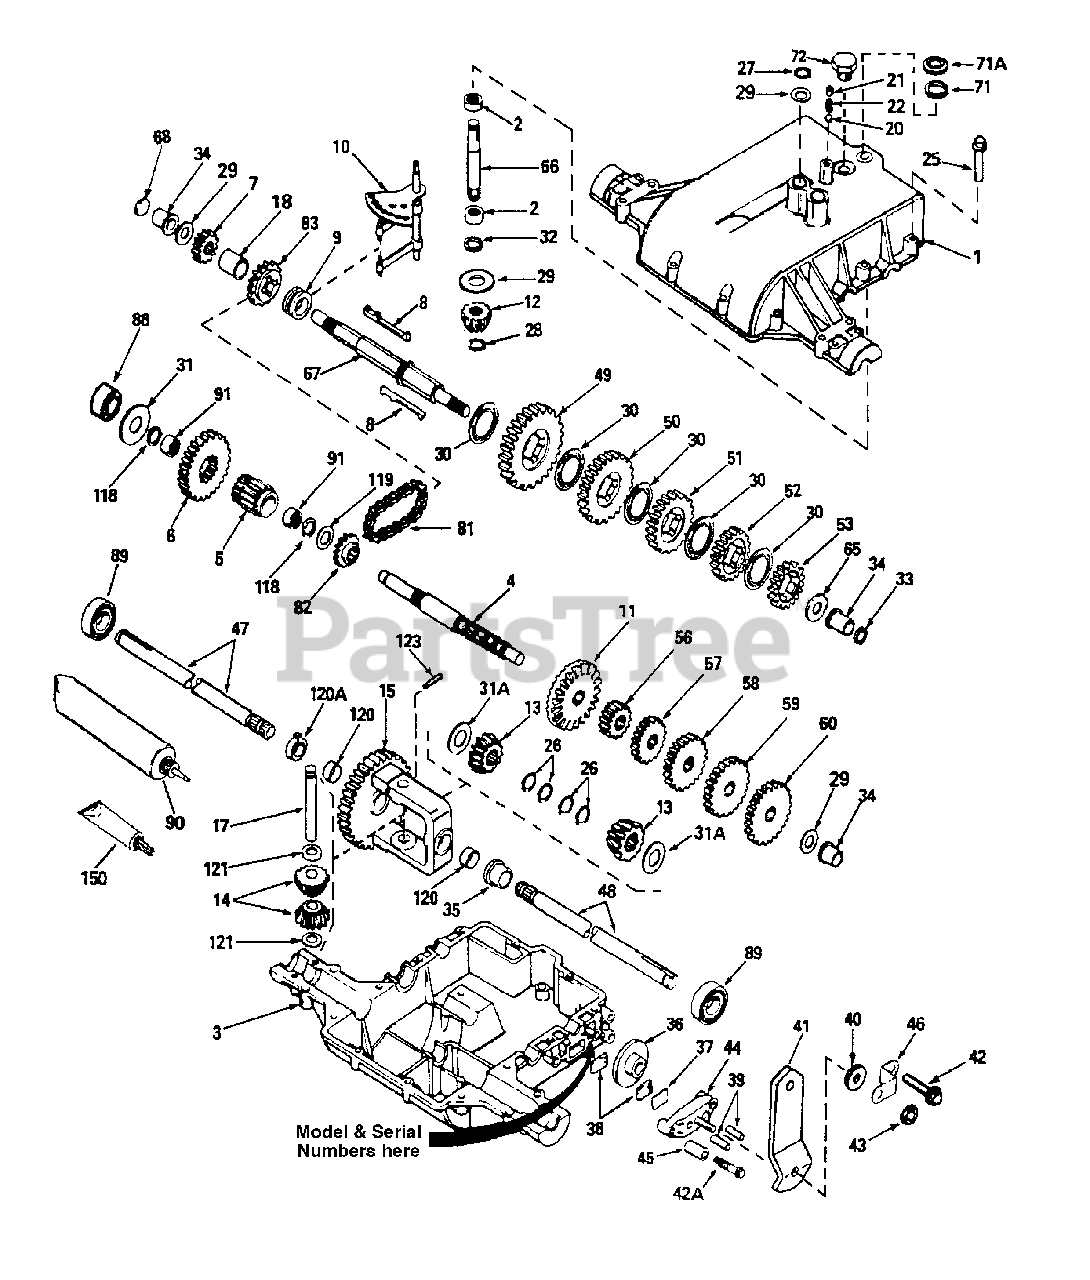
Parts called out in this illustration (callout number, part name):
1	Transaxle Cover
2	Needle Bearing
3	Transaxle Case
4	Countershaft
5	Output Pinion
6	Output Gear (35 teeth)
7	Spur Gear (15 teeth)
8	Shift Key
9	Shift Collar
10	Shift Fork
11	Bevel Gear (42 teeth)
12	Input Bevel Pinion
13	Bevel Gear (16 teeth)
14	Bevel Pinion (16 teeth)
15	Differential Gear Assy.
17	Drive Pin
20	Ball, 5/16" dia.
21	Set Screw, 3/8-16 x 3/8
25	Screw, 1/4-20 x 1-1/4
26	Retaining Ring
27	Retaining Ring
28	Retaining Ring
33	Square Cut Ring
34	Flanged Bushing
35	Flanged Bushing
36	Brake Disk
37	Brake Pad Plate
38	Brake Pad (Pkg of 2)
39	Dowel Pin
41	Brake Lever
42	Screw, 1/4-20 x 1-1/4
42A	Screw, 1/4-20 x 2-1/4
43	Locknut, 5/16-24
44	Brake Pad Holder
46	Brake Lever Bracket
47	Axle (12-1/2" long)
48	Axle (14-3/4" long)
49	Spur Gear (37 teeth)
50	Spur Gear (30 teeth)
51	Spur Gear (25 teeth)
52	Spur Gear (22 teeth)
53	Spur Gear (20 teeth)
56	Spur Gear (12 teeth)
57	Spur Gear (20 teeth)
58	Spur Gear (25 teeth)
59	Spur Gear (28 teeth)
60	Spur Gear (30 teeth)
66	Input Shaft
67	Shifter & Brake Shaft
71	Square Cut Ring
71A	Pushnut, 1/2"
72	Threaded Plug
81	Roller Chain (No. 40 chain, 22 links)
82	Sprocket (10 teeth)
83	Sprocket (14 teeth)
88	Ball Bearing
89	Ball Bearing
90	Grease (32 oz. bottle Bentonite grease)
91	Needle Bearing
118	Square Cut Ring
123	Roll Pin
150	Gasket Eliminator (Loctite #515)
